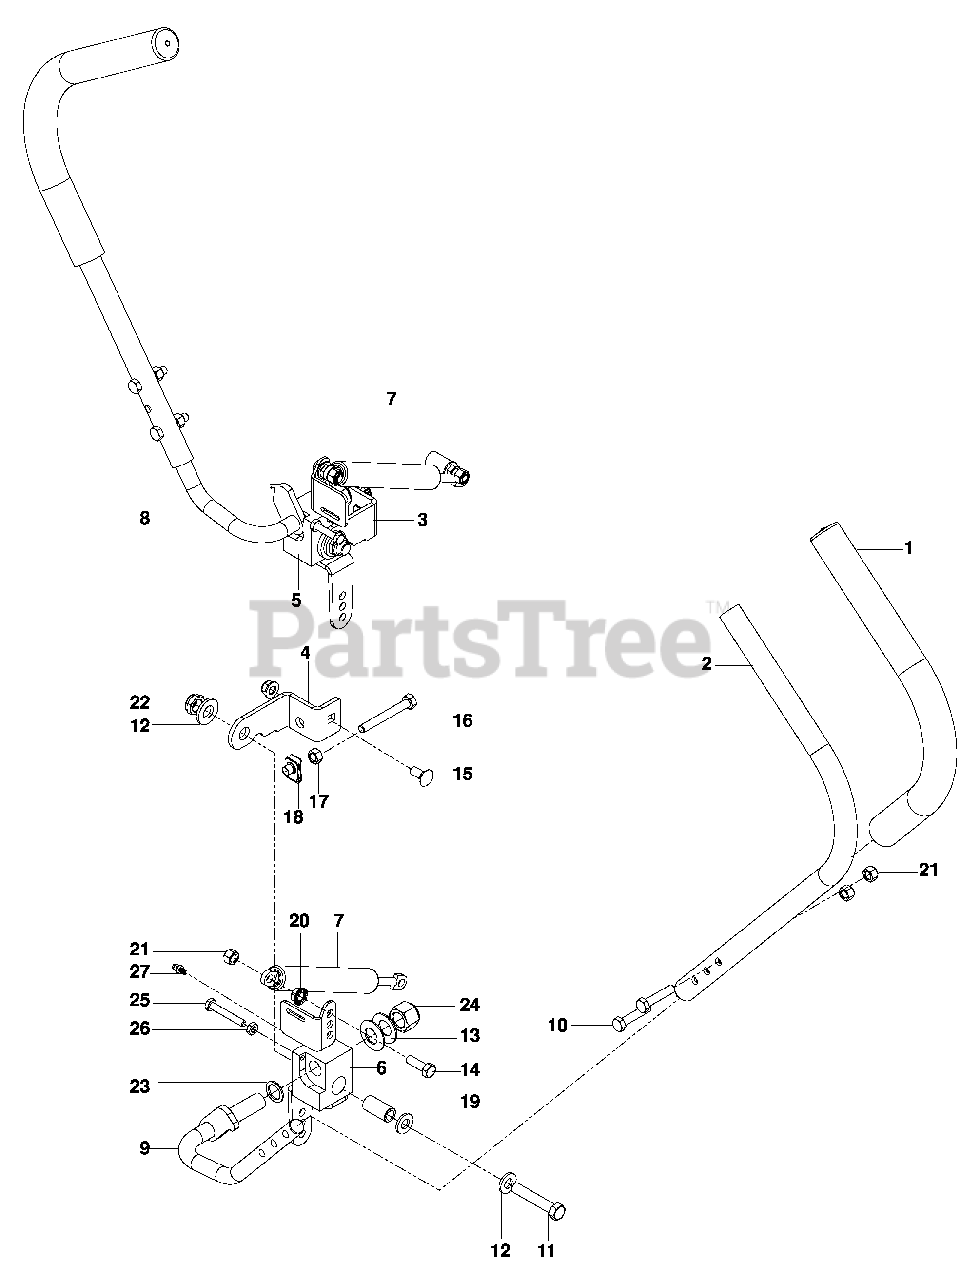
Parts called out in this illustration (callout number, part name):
2	LEVER, UPPER
3	STOP, STEER CNTRL RH
4	STOP, STEER CNTRL LH
8	LOWER LEVER, RH
9	LOWER LEVER, LH
10	BOLT, HEX HD 5/16-18 x 1½
11	BOLT, HEX HD ½-13 x 2¾
12	WASHER ½ SAE
13	WASHER 5/8 BELLEVILLE
14	BOLT, HEX HD 5/16-18 x 1
15	BOLT, RD HD 5/16-18 x ¾
16	BOLT, HEX 5/16-18 x 2½ TPBLT
17	NUT, 5/16-18 HEX
18	U TYPE RETAINER
19	BUSHING ½ ID x ¾ OD
20	NUT 5/16-18 HEX WHIZLK
21	NUT 5/16-18 HEX NYLOC
22	NUT ½-13 JAM NYLOC GR 2
23	WASHER, SPECIAL
24	NUT 5/8-11 NYLOC
25	BOLT, HEX HD ¼-20 x 1¾
26	NUT ¼-20 JAM
27	ZERK
